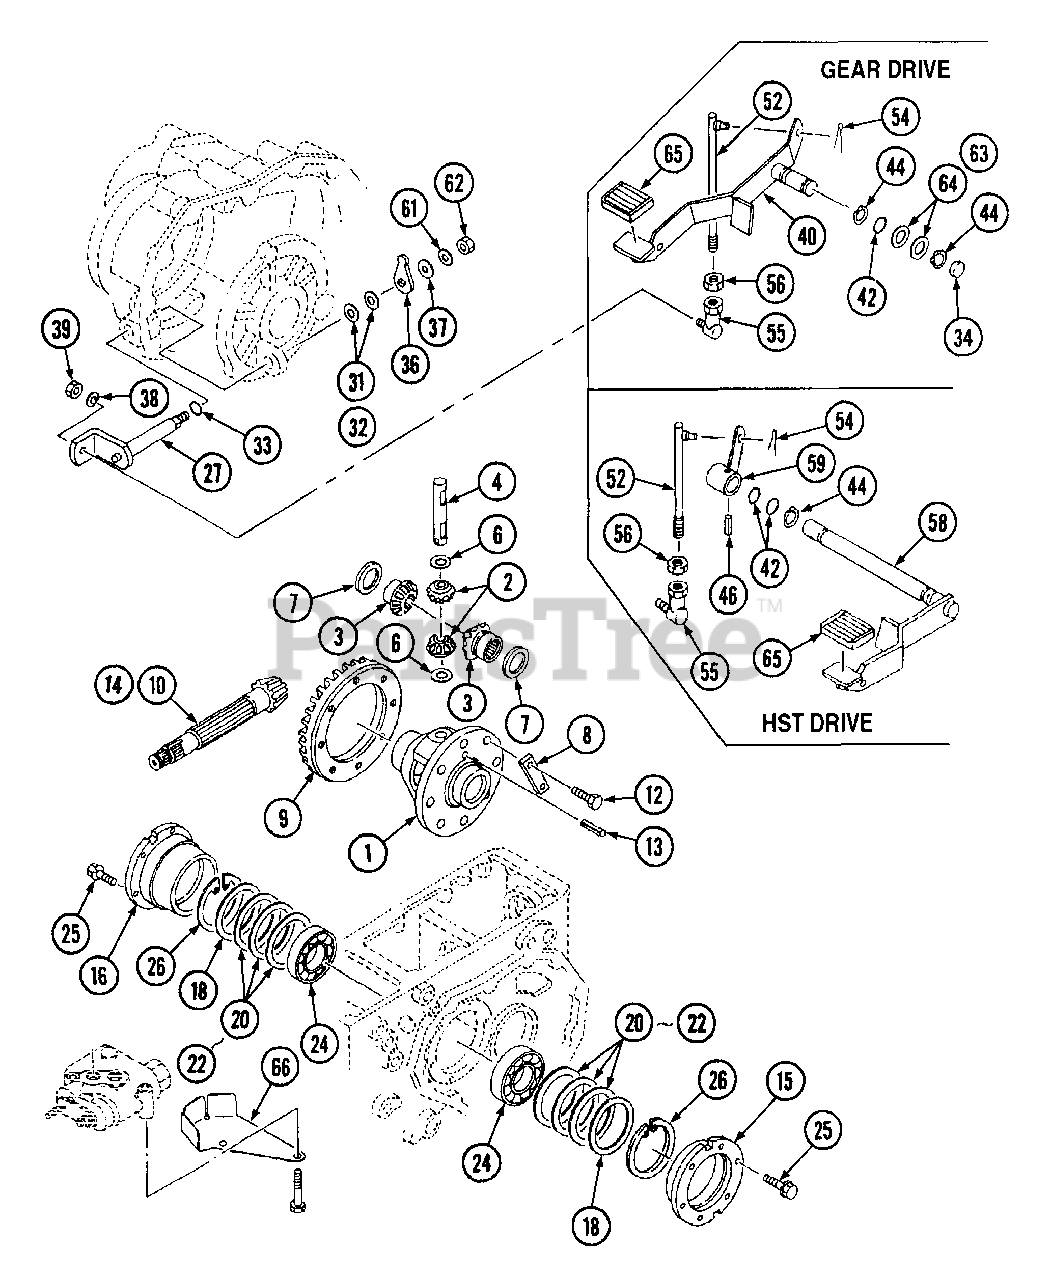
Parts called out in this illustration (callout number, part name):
4	Shaft, Pinion
6	Washer, Thrust
7	Washer, Thrust
9	7-35 Gear Set,
10	Shaft, Pinion
14	7-35 Gear Set,
33	O-Ring
40	Pedal Diff. Lock
46	Pin, Spring
58	Pedal Diff. Lock
59	Arm, Diff.
